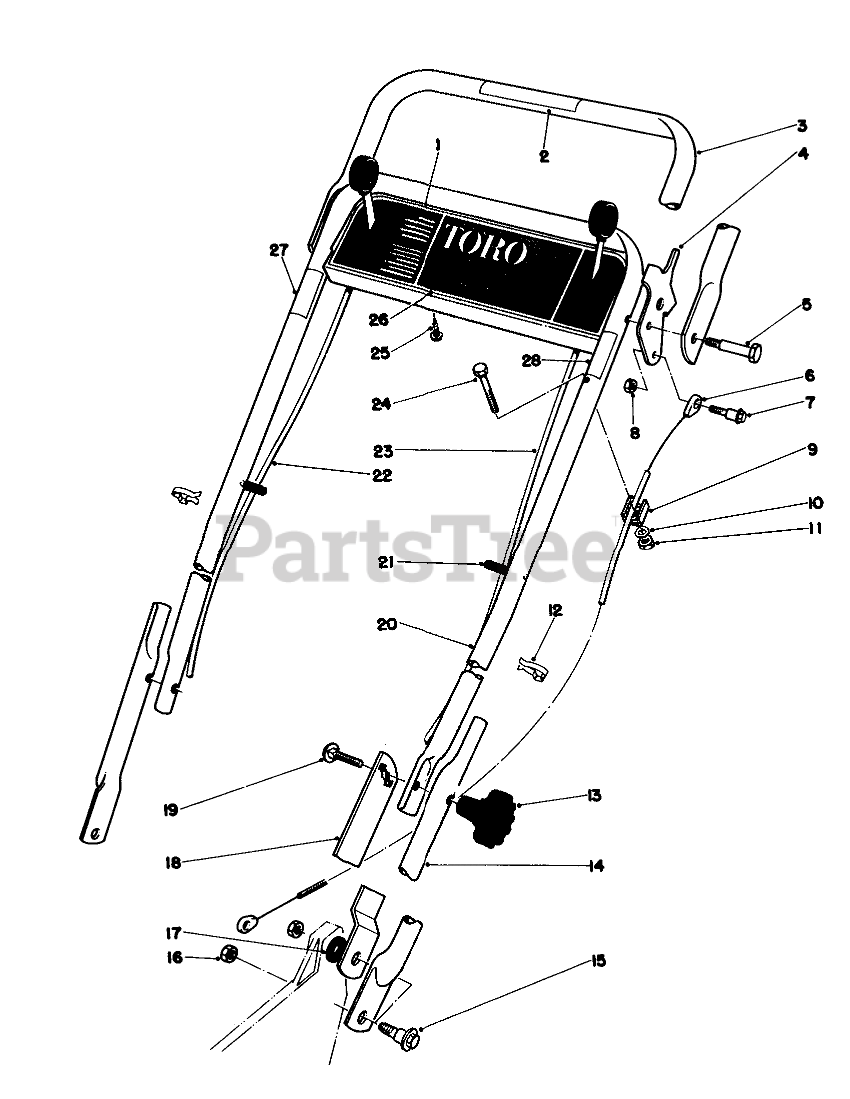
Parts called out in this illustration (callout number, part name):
1	Control Panel
2	Decal-Traction Handle (French & Dutch)
3	Demand Handle
4	Demand Handle Stop
5	BOLT-SHOULDER
6	DEMAND HANDLE CABLE
7	Shoulder Bolt
8	NUT-HEX, SIDE DEFORM
9	CLAMP-CABLE
10	WASHER-FLAT
11	NUT-LOCK, NI
12	BOWDEN CLIP
14	LOWER HANDLE
15	SCREW-SHOULDER
16	Nut
17	SPACER
18	Handle Latch L.H.
19	SCREW-CARR
20	Upper Handle
21	CAP-VINYL
22	GROUND SPEED CONTROL
23	Throttle Control
24	SCREW-HH
25	SCREW-HWHTF
26	Decal-Control Panel
27	Decal-Control Shift (French & Dutch)
28	Decal Throttle Control
